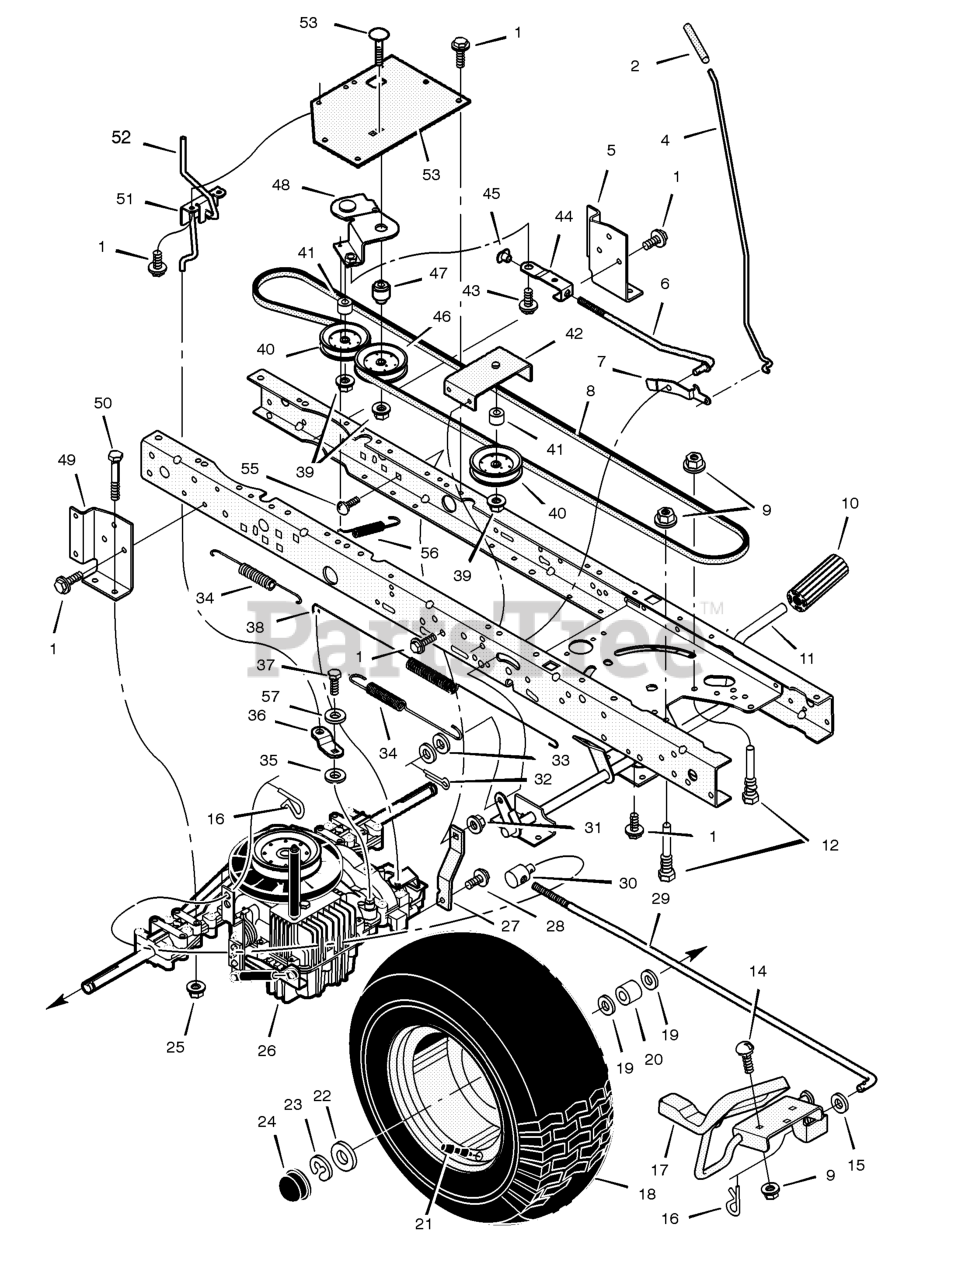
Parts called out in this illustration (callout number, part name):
2	Grip, Parking Brake
4	Rod, Parking Brake
5	Bracket, Transaxle - Left
6	Rod, Clutch
7	Latch, Parking Brake
8	V-Belt, Drive
9	Nut, Flange
10	Pedal, Brake/Clutch
11	Assembly, Brake Pedal
12	Screw, Guide
14	Bolt, Carriage
16	Pin, Hair
17	Pedal Assembly, Hydro
18	Wheel & Tire Ass'y - Rear 20"
20	Spacer
21	Stem, Valve
24	Cap, Hub
25	Nut, Centerlock
26	Transaxle **
27	Strap, Torque
29	Rod, Control
30	NUT, Adjusting, 1/2-13
31	Nut, Centerlock
32	Pin, Cotter
34	Spring, Extension
36	ARM, Disconnect
37	Capscrew
38	Spring, Brake
39	Locknut, Flange
40	Pulley, Idler
42	Bracket, Idler Assembly
43	Bolt, Shoulder
44	Link, Clutch
45	Nut, Tee
46	Pulley, Idler
47	Bushing, Pivot
48	Arm Assembly, Idler
49	Bracket, Transaxle-Right
50	Bolt, Hex
51	Bracket, Disconnect
52	Rod, Disconnect
53	Bracket, Idler Pivot
54	Bolt, Carriage
55	Bolt, Carriage
56	Spring, Clutch
